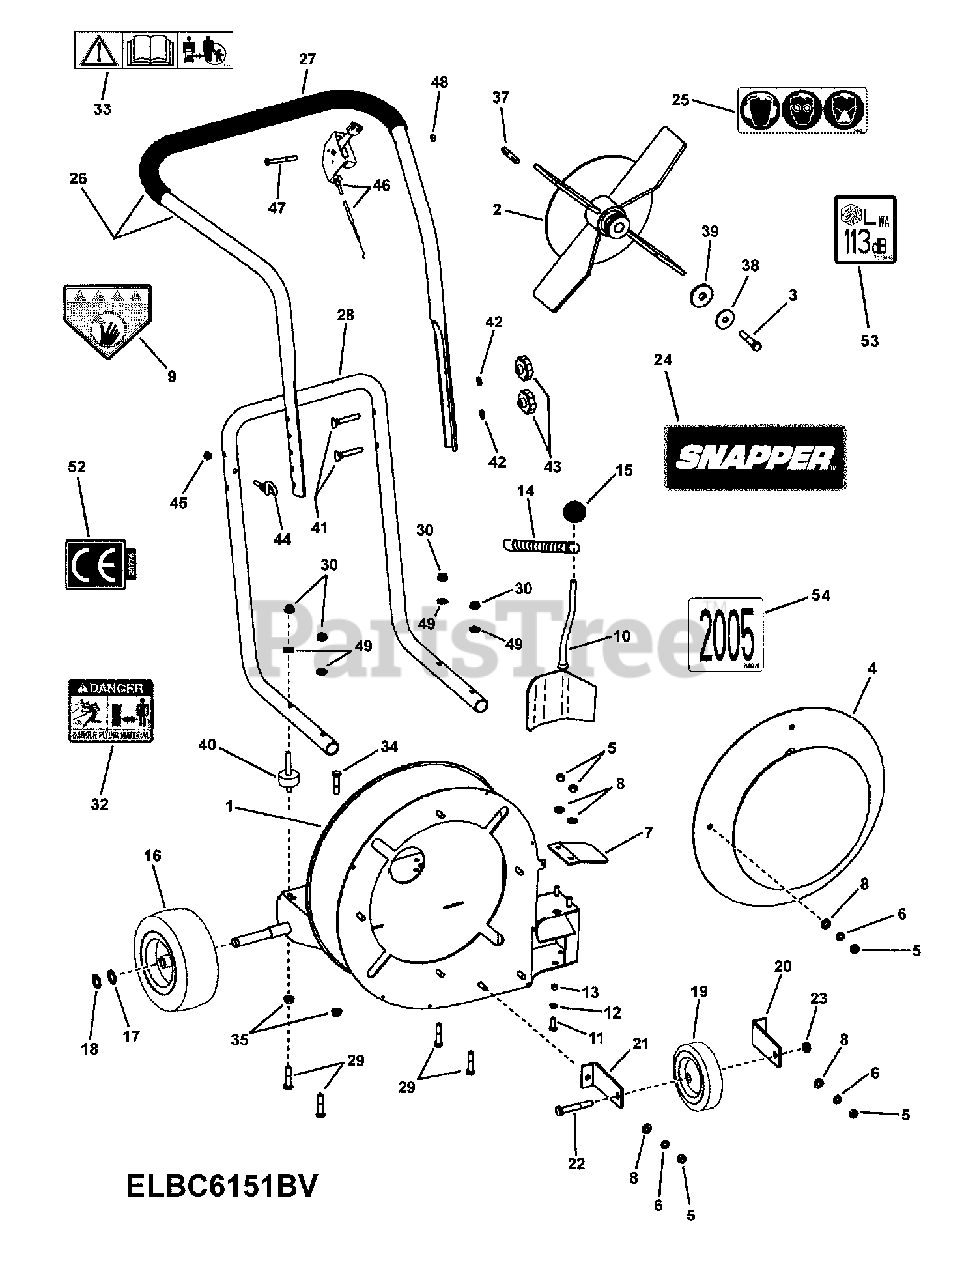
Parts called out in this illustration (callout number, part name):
1	WELDMENT, Base & Housing, 52 Classic
2	WELDMENT, Steel Impeller, 4 Blade, 15.00 O.D.
3	SCREW, 3/8-24 x 2" Hex Head Cap, GR 5
4	WELDMENT, Intake Baffle
5	NUT, 5/16-18 Hex, GR 5 or B
6	WASHER, 5/16" Split
7	DEFLECTOR, Side Air
8	WASHER, .34 x .69 x .08 Flat
9	DECAL, Danger, Cut Finger (Euro)
10	WELDMENT, Door Front/Side Discharge
11	SCREW, 1/4-20 x 3/4" Hex Head Cap, GR 5
12	WASHER, .263 x .375 x .062 Split Lock
13	BUSHING, Steel Sleeve .250 I.D. x .375 O.D. x .25 long
14	SPRING, Extension
15	KNOB, #230 Dimco (3/8-16 thread)
16	*ASSY, Wheel & Tire, Sawtooth 4.10/3.50-4 Kenda
17	WASHER, .64 x .99 x .05 Flat
18	RING, External Retaining
19	WHEEL, 6.00 x 1.50 Semi-Pneumatic
20	BRACKET, Caster- RH
21	BRACKET, Caster- LH
22	SCREW, 3/8-16 x 2-1/2" Hex Head Cap, GR 5
23	NUT, 3/8-16 Hex Center Lock, GR 5 or B
24	DECAL, SNAPPER (Panel)
25	DECAL, Personal Protection
26	ASSEMBLY, Upper Handle & Grip- Narrow
27	GRIP, 1.0 x 21-1/2" Foam
28	HANDLE, Lower Folding, Narrow, Blower
29	SCREW, 5/16-18 x 1-3/4" Hex Head Cap, GR 5
30	NUT, 5/16-18 Hex Nyloc
32	DECAL, Danger, Thrown Objects
33	DECAL, Caution, Symbols
34	SCREW, 5/16-18 x 1-1/2" Hex Head Cap, GR 5
35	NUT, 5/16-18 Hex Flange Lock, GR 5
37	KEY, 1/4" Square x 2"
38	WASHER, .411/.406 I.D. Cone
39	WASHER, .468 x 1.625 x .25 Flat
40	***MOUNT, Vibration (5/16-18 threads, both ends)
41	BOLT, 5/16-18 x 2" Curved Head Square Neck, GR 2
42	WASHER, 5/16" Internal Tooth Lock
43	KNOB, Folding Handle
44	ROPE GUIDE (1/4-20 thread)
45	NUT, 1/4-20 Hex Center Lock, GR 5 or B
46	THROTTLE CONTROL, B&S, 35.00/1.62
47	SCREW, 1/4-20 x 2" Hex Head Cap, GR 5
48	NUT, 1/4-20 Hex Nyloc
49	WASHER, 5/16" Curved
52	DECAL, Euro Community (CE)
53	DECAL, Sound 113 dB
54	DECAL, 2005 Year of Manufacture
